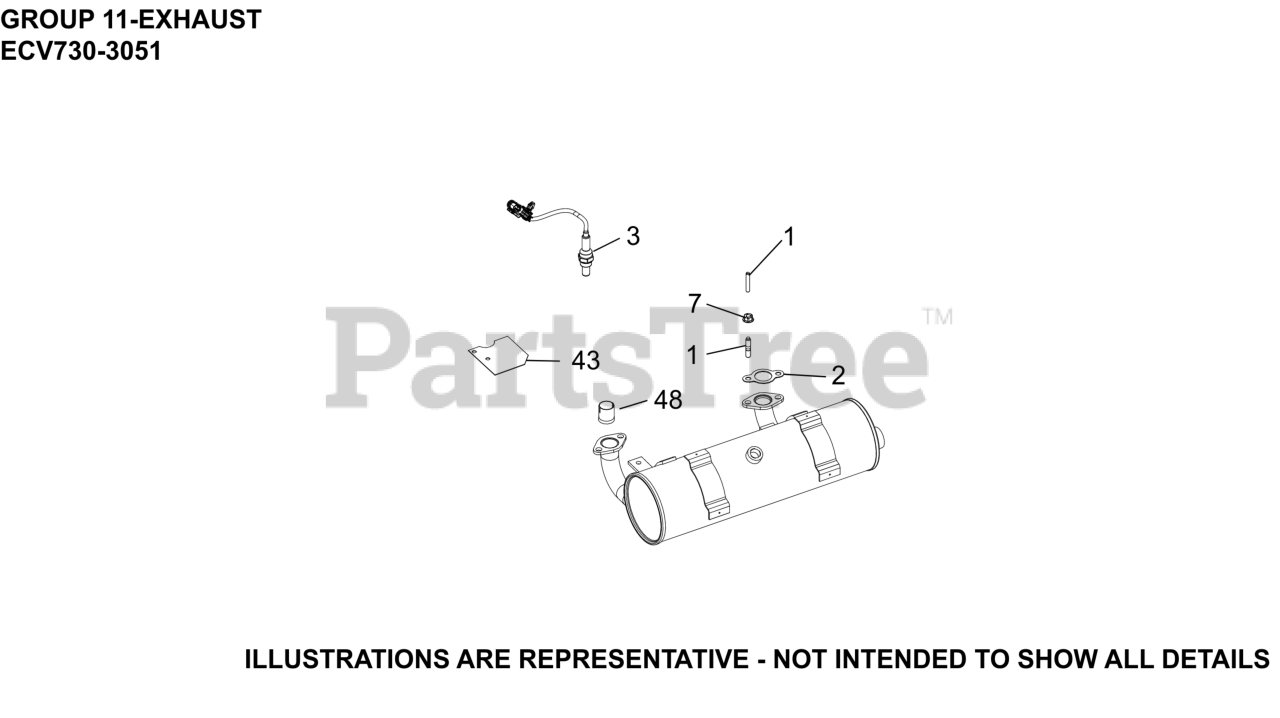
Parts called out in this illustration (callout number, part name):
1	STUD, M6X1.0X36
1	STUD, METRIC EXHAUST
2	GASKET, EXHAUST MANIFOLD
3	SENSOR, OXYGEN (M18 x 1.5 THREADS)
7	NUT, HEX FLANGE LOCK (M8)
43	DEFLECTOR, HEAT
48	LINER, EXHAUST PORT
